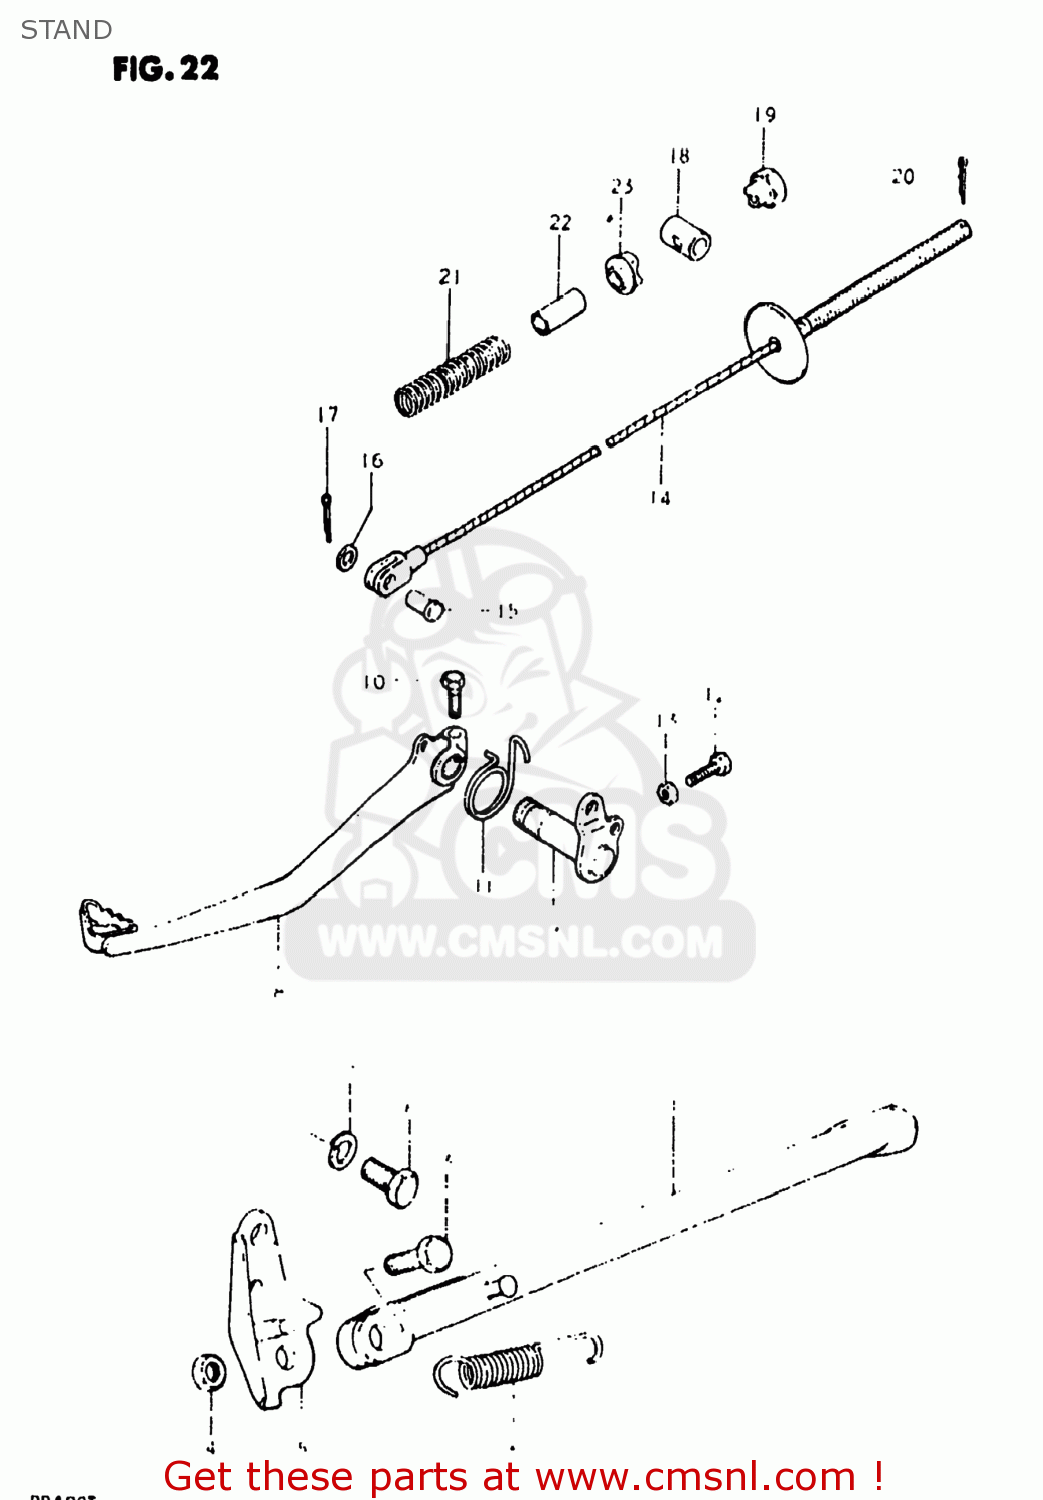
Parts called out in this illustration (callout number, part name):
1	STAND,SIDE
2	SPRING
3	BOLT(10X30)
4	NUT
5	BRACKET,PROP STAND
6	BOLT(10X19)
7	LOCK WASHER
8	PEDAL,BRAKE
9	ARM,BRAKE PEDAL
10	BOLT
11	SPRING
12	BOLT(6X23)
13	NUT
14	CABLE,RR BRAKE
15	PIN(L:17.5)
16	WASHER
17	PIN
18	PIN,BRAKE CABLE ADJUSTER
19	NUT
20	PIN
21	SPRING
22	CUSHION,FR GRILLE,UPPER
23	CUSHION
